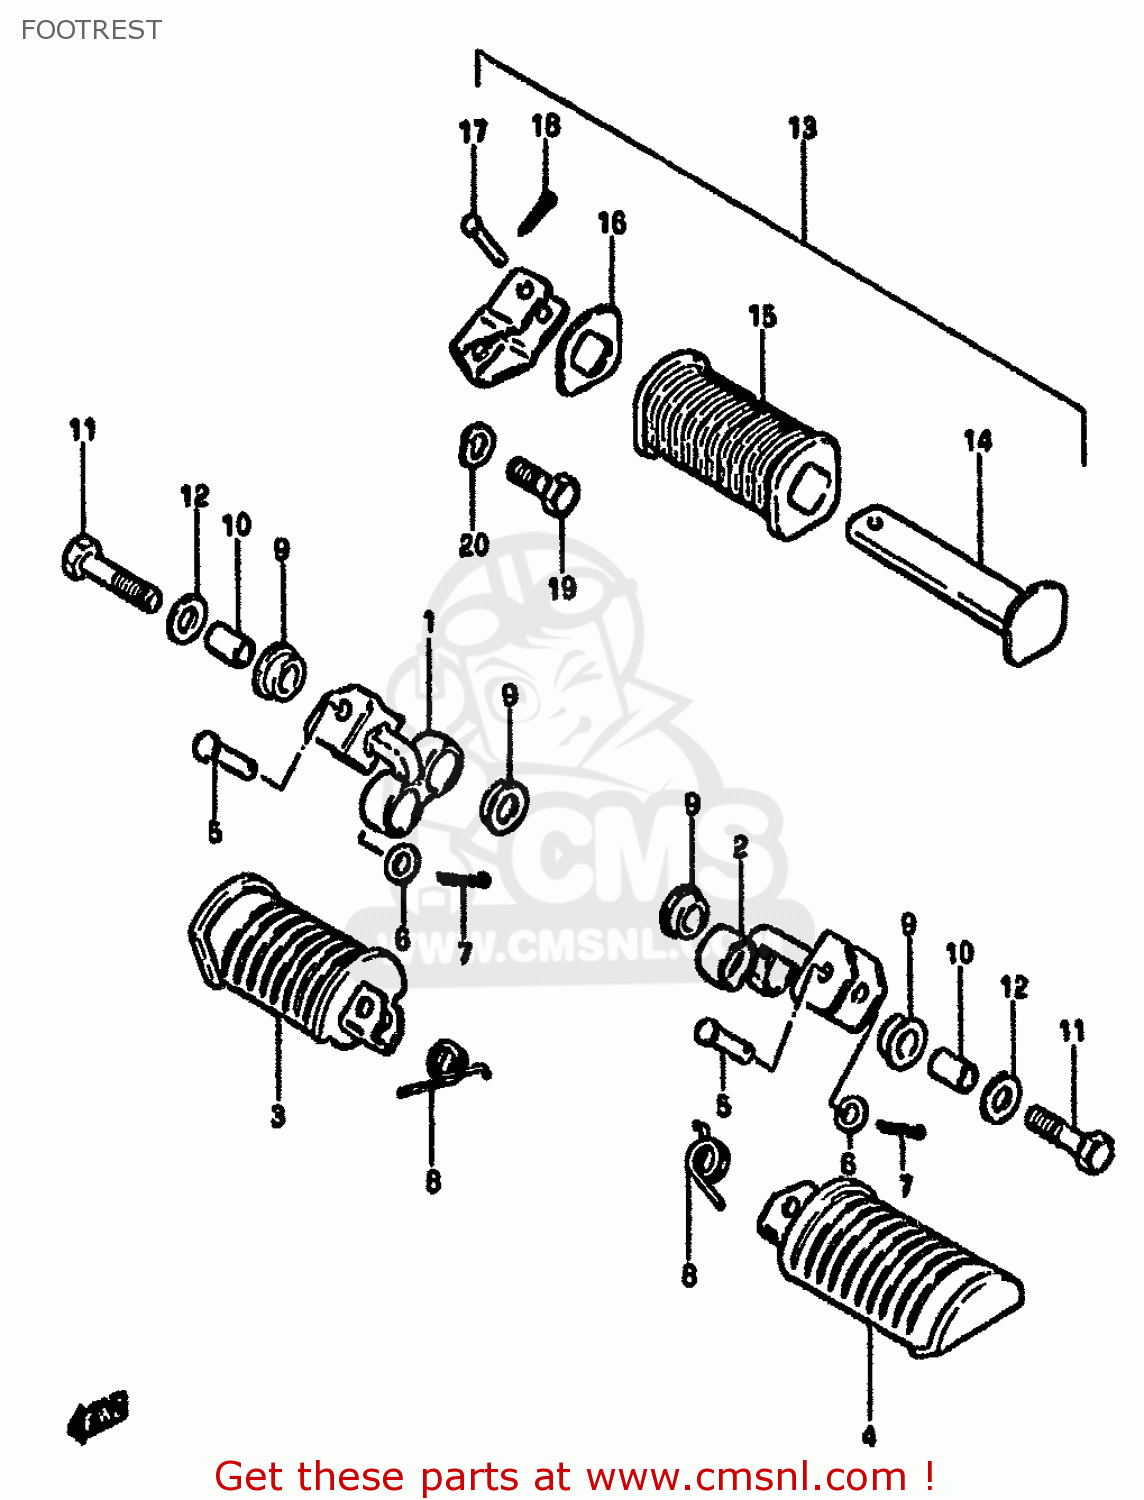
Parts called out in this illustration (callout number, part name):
1	BAR,FOOTREST RH
2	BAR,FOOTREST LH
3	RUBBER,FR FOOT
4	RUBBER, LH
5	PIN
6	WASHER
7	PIN
8	SPRING
9	BUSH
10	SPACER (10.2X14X20)
11	BOLT 10X40
12	WASHER(10.2X28X2.3)
13	FOOTREST ASSEMBLY,REAR,LEFT
14	BAR,REAR FOOTREST,LEFT
15	RUBBER,PILLION FOOTREST
16	WASHER,PILLION FOOTREST RUBBER
17	PIN
18	PIN
19	BOLT 10X20
20	LOCK WASHER
